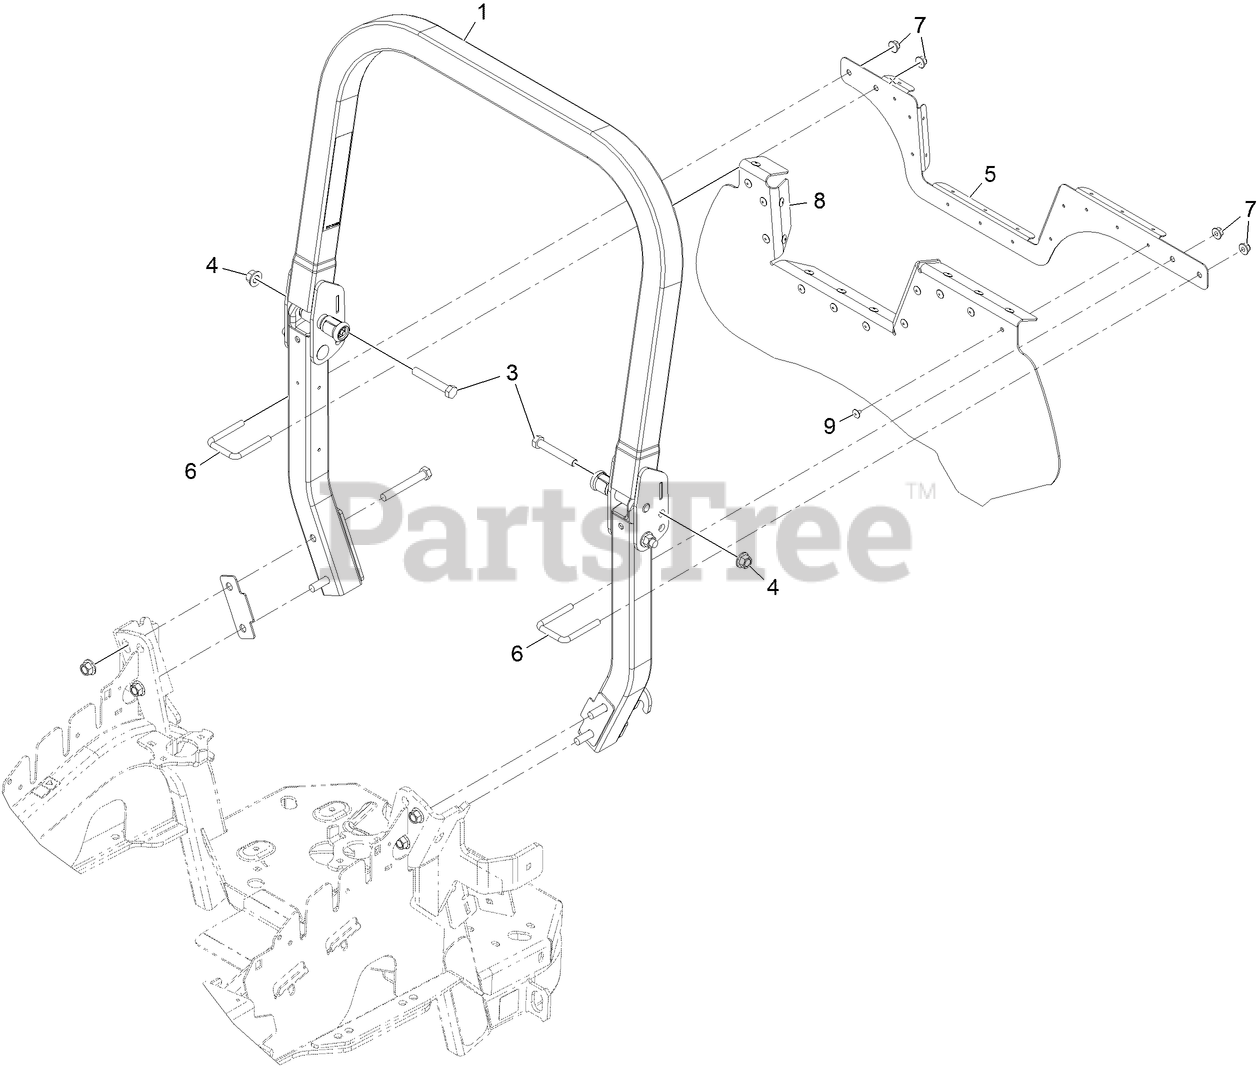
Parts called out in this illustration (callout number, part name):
1	ASM,ROPS SERVICE EXMARK
3	SCREW-HH
4	Nut-Lock 1/2-13
5	BRACKET, AIR DAM
7	NUT-HF, NI
8	AIR DAM, HOOD
9	RIVET-POP
